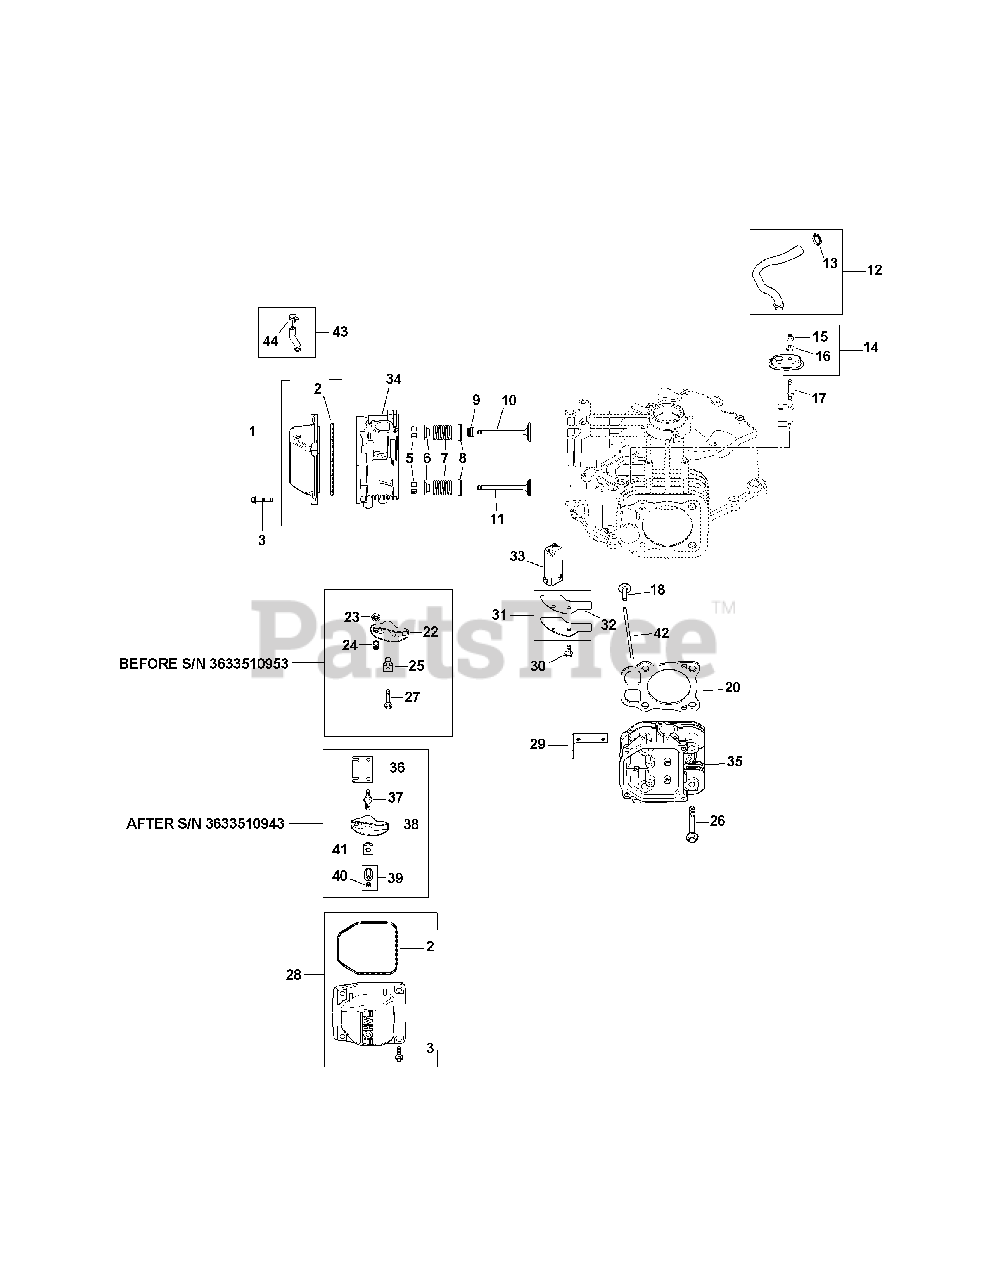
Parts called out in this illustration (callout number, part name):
1	Breather Valve Cover Kit (Inc. 2)
2	Valve Cover O-Ring
3	Flg. Screw, M6 X 1.0 X 30
5	Retainer Kit
6	Valve Spring Cap
7	Valve Spring
8	Spring Retainer
9	Valve Stem Seal
10	Intake Valve (Std)
11	Exhaust Valve (Std)
12	Kit, Breather Hose Kit (Inc. 13)
13	Hose Clamp, 1/2
14	Breather Housing Kit (Inc. 15, 16)
15	Lock Nut, M 5 X .8
16	Sealing Washer
17	Breather Cover Stud
20	Cylinder Head Gasket Kit
26	Flg. Screw, M 10 X 1.5 X 90
28	Breather Valve Cover Kit (Inc. 2 & 3)
29	Lifting Strap
30	Flg. Thd. Frm. Screw, M6 X 1.0 X 16
31	Breather Cover Kit (Inc. 32)
33	Breather Filter
34	#1 Cylinder Head Assembly Kit
35	#2 Cylinder Head Assembly Kit
39	Hex Nut Assembly (Includes 40)
41	Rocker Arm Pivot
43	Fuel Pump Hose w/ Clamp Kit (Inc.44)
